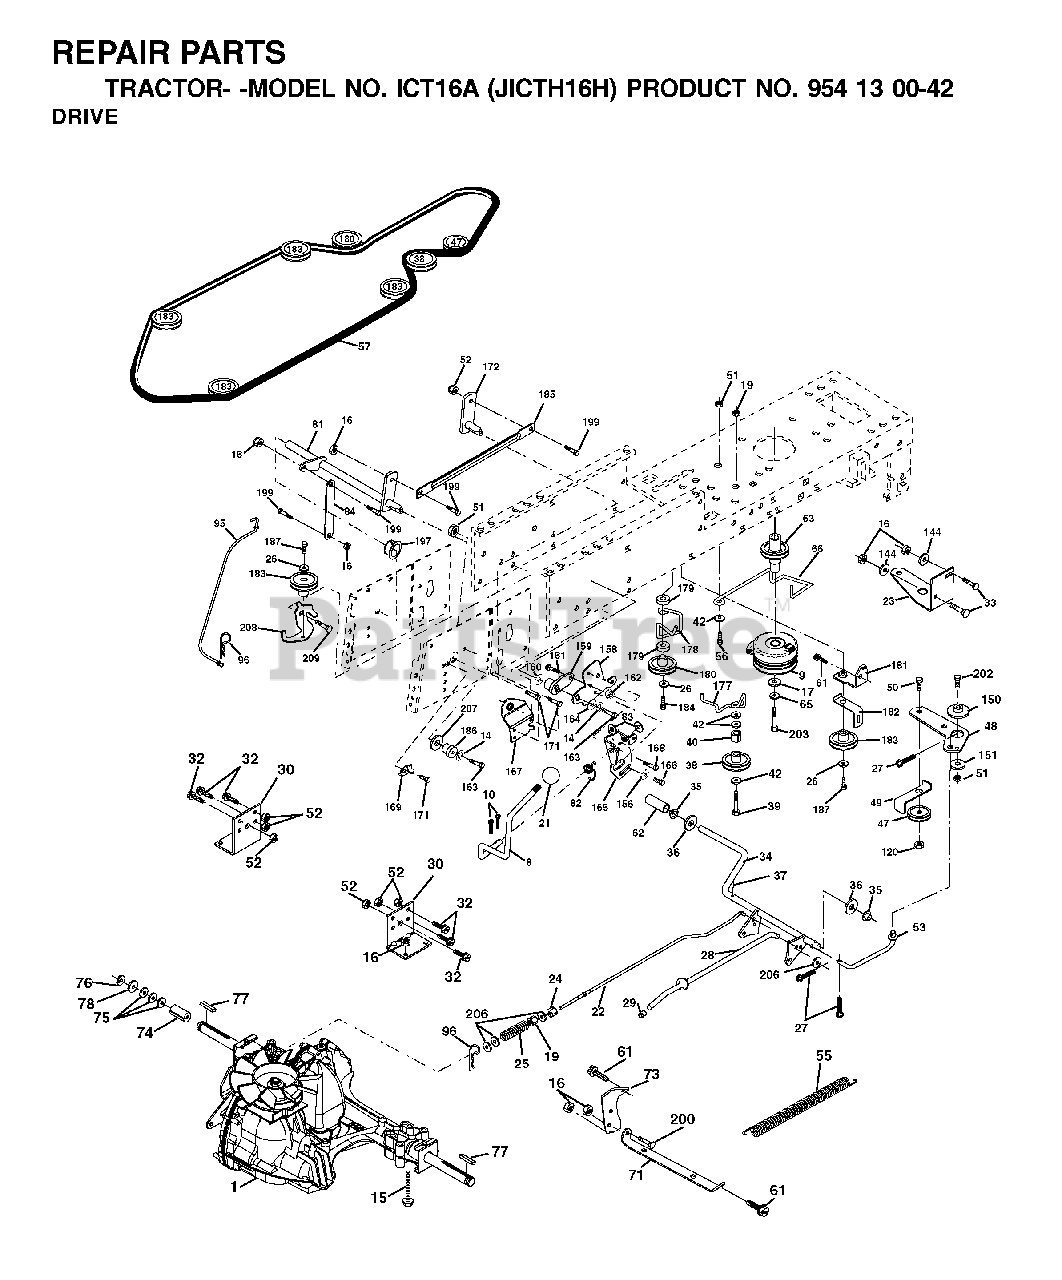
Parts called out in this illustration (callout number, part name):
8	ROD SHIFT
10	PIN COTTER
14	LOCKWASHER
15	BOLT HEX 5/16-18 GR 5
16	NUT.71038.31-18.HEX.NYLOCK
19	NUT
21	PISTOL KNOB
23	BRACKET
24	NUT
25	SPRING ROD LT
27	COTTER PIN
28	ROD BRAKE PARK LT
29	PLUNGER CAP
30	BRKT, TRNSXLE MNT 20"
32	BOLT
33	BOLT
35	BEARING.NYLON
36	WASHER LT
37	DRIVE PIN
38	PULLEY.FLAT
42	WASHER
47	IDLER PULLEY
48	BELLCRANK, CLUTCH
49	RETAIN BELT
50	BOLT
51	LOCKNUT
52	LOCKNUT
53	LINK, CLUTCH LT
55	SPRING, RETURN LT
56	BOLT.3/8-16X1.50
61	SCREW 3/8-16X3/4
62	PEDAL COVER T
63	PULLEY, CLUTCH ELECT EVX
65	LOCKWASHER
66	KEEPER BELT ENGINE
71	STRAP TORQUE LH HYDRO
73	STRAP TORQUE RH HYDRO
74	SPACER AXLE
76	E-RING LT
77	SQUARE KEY
81	SHAFT ASSY
82	SPRING,TORSION
83	WASHER
96	RETAINER M
120	NUT LOCK FLG 3/8-16 UNC
144	WASHER
150	BUSHING.BELLCRANK.GRD.DR
151	WASHER 12/32X2X10GA
156	WASHER.SRRTD.5/16
158	BRACKET
159	HUB
161	BOLT
162	NUT.CROWNLOCK.1/4
165	RP BRACKET
167	BRACKET
168	BOLT.SHOULDER.5/16-18X
169	PLATE.FASTENING.CROSS.SHAFT
180	PULLEY.FLAT.IDLER
182	KEEPER BELT
183	PULLEY.V-IDLER
184	SCREW.HXWSH.3/8
187	SCREW.3/8-16
197	NYLINER SNAP 5/8" ID
199	BOLT SHOULDER 5/16-18 UNC
200	BOLT
202	BOLT.3/8-16X1.50
206	WASHER
207	WASHER NYL
